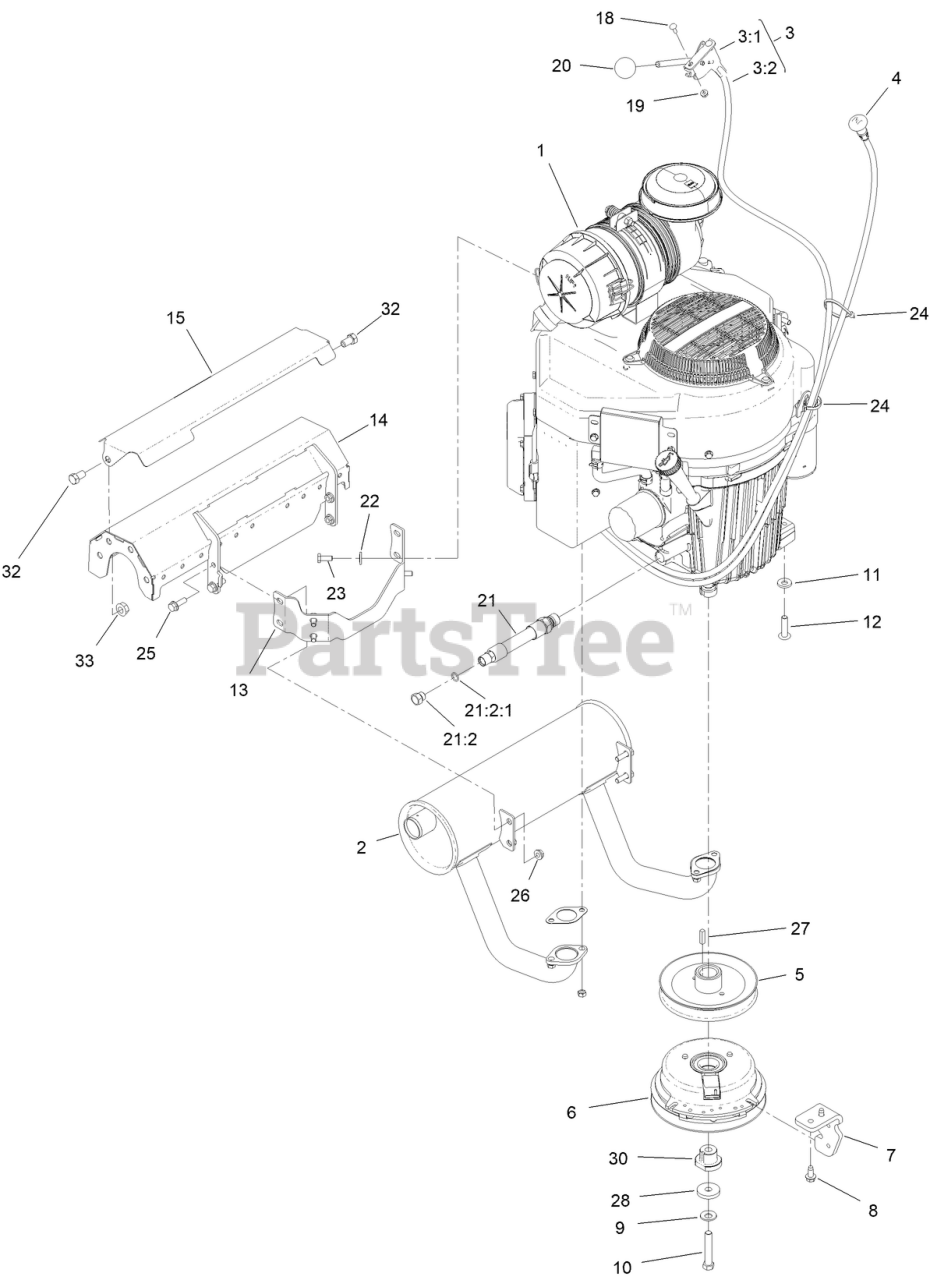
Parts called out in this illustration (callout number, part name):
1:1	KAWASAKI 49065-7007 ENGINE OIL FILTER
1:2	KAWASAKI 11013-7044 ENGINE AIR FILTER
1:3	KAWASAKI 11013-7045 SAFETY FILTER
2	MUFFLER, KAWI FX921
3	THROTTLE ASM
3:1	LEVER-CONTROL
3:2	CABLE-THROTTLE
4	CABLE-CHOKE
5	PULLEY
6	CLUTCH-200CMS
7	BRACKET, CLUTCH STOP
8	SCREW-HWHTF
9	WASHER-SPRING
10	SCREW-HH
11	WASHER-BELLEVILLE
12	SCREW-BHTF
13	BRACKET-MUFFLER
14	MUFFLER GUARD ASM
15	SHIELD-HEAT
18	BOLT-CARR
19	NUT-LOCK, FLANGE
20	KNOB-BALL
21	HOSE ASM
21:2	PLUG-HH
21:2:1	O-RING
22	WASHER-SPRING
23	SCREW-HH
24	TIE-CABLE
25	SCREW-HHF
26	NUT-HF
28	WASHER
30	SPACER, D-DRIVE
32	SCREW-HH
33	NUT-HF
